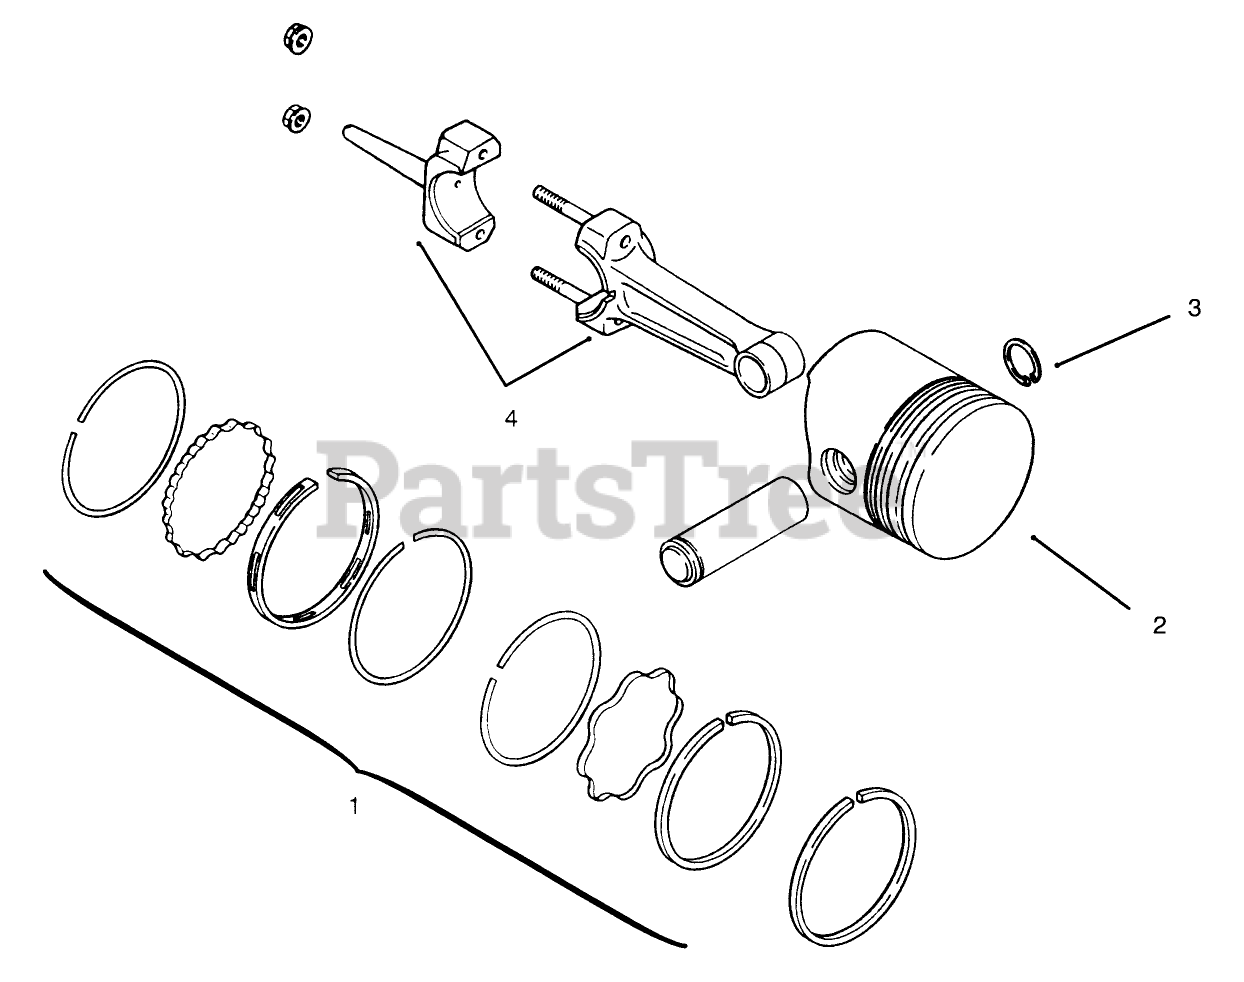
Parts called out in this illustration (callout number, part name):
1	Set-Ring STD .003 14hp
2	Piston-Ring Set STD 14hp
3	Retainer
4	Rod-Connecting STD
